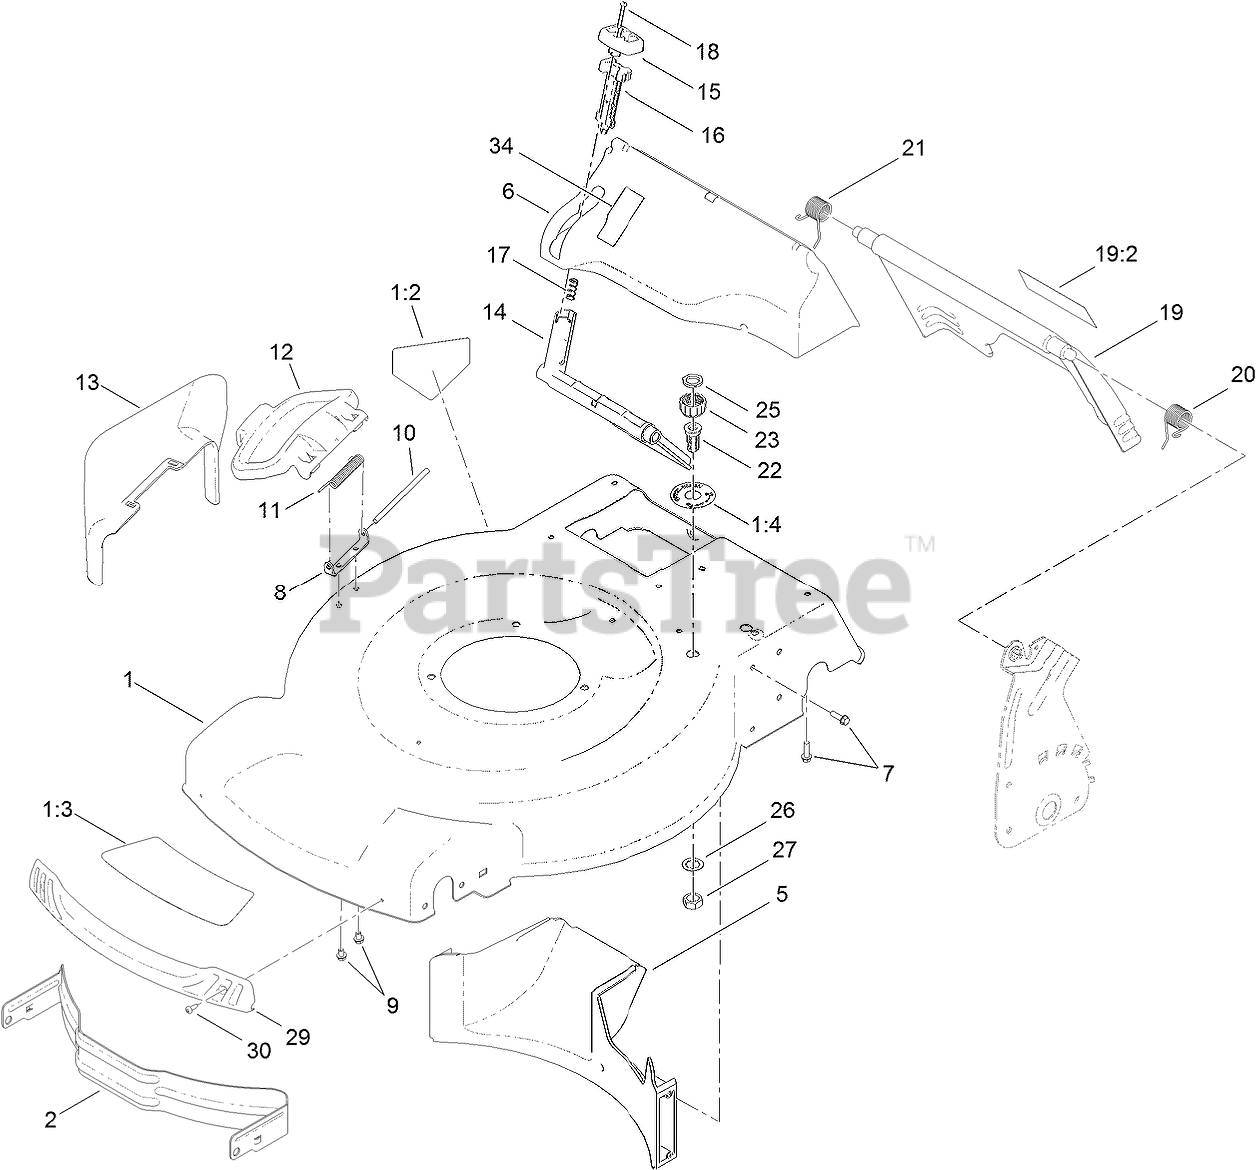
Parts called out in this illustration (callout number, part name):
1	HOUSING ASM
1:2	DECAL-DANGER
1:3	DECAL-RECYCLER
1:4	DECAL-PORT, WASHOUT
2	BAFFLE-FRONT
5	BAFFLE-REAR
6	CHUTE-RECYCLE
7	SCREW-HWH
8	BRACKET-COVER
9	SCREW-HWH
10	ROD-COVER
11	SPRING-TORSION
12	DEFLECTOR-SIDE
13	CHUTE-DISCHARGE, SIDE
14	DEFLECTOR-RECYCLE
15	KNOB-RECYCLE
16	LATCH-RECYCLE
17	SPRING-COMPRESSION
18	SCREW-PPH
19	REAR DOOR ASM
19:2	DECAL-WARNING
20	SPRING-TORSION
21	SPRING-TORSION
22	PORT-WASHOUT
23	COUPLING-HOSE, WASHOUT PORT
25	WASHER-SEAL, WASHOUT PORT
26	WASHER-TOOTH, INTERNAL
27	NUT-JAM
29	BUMPER
30	SCREW-FORMING, THREAD
34	DECAL-BAG ON DEMAND
